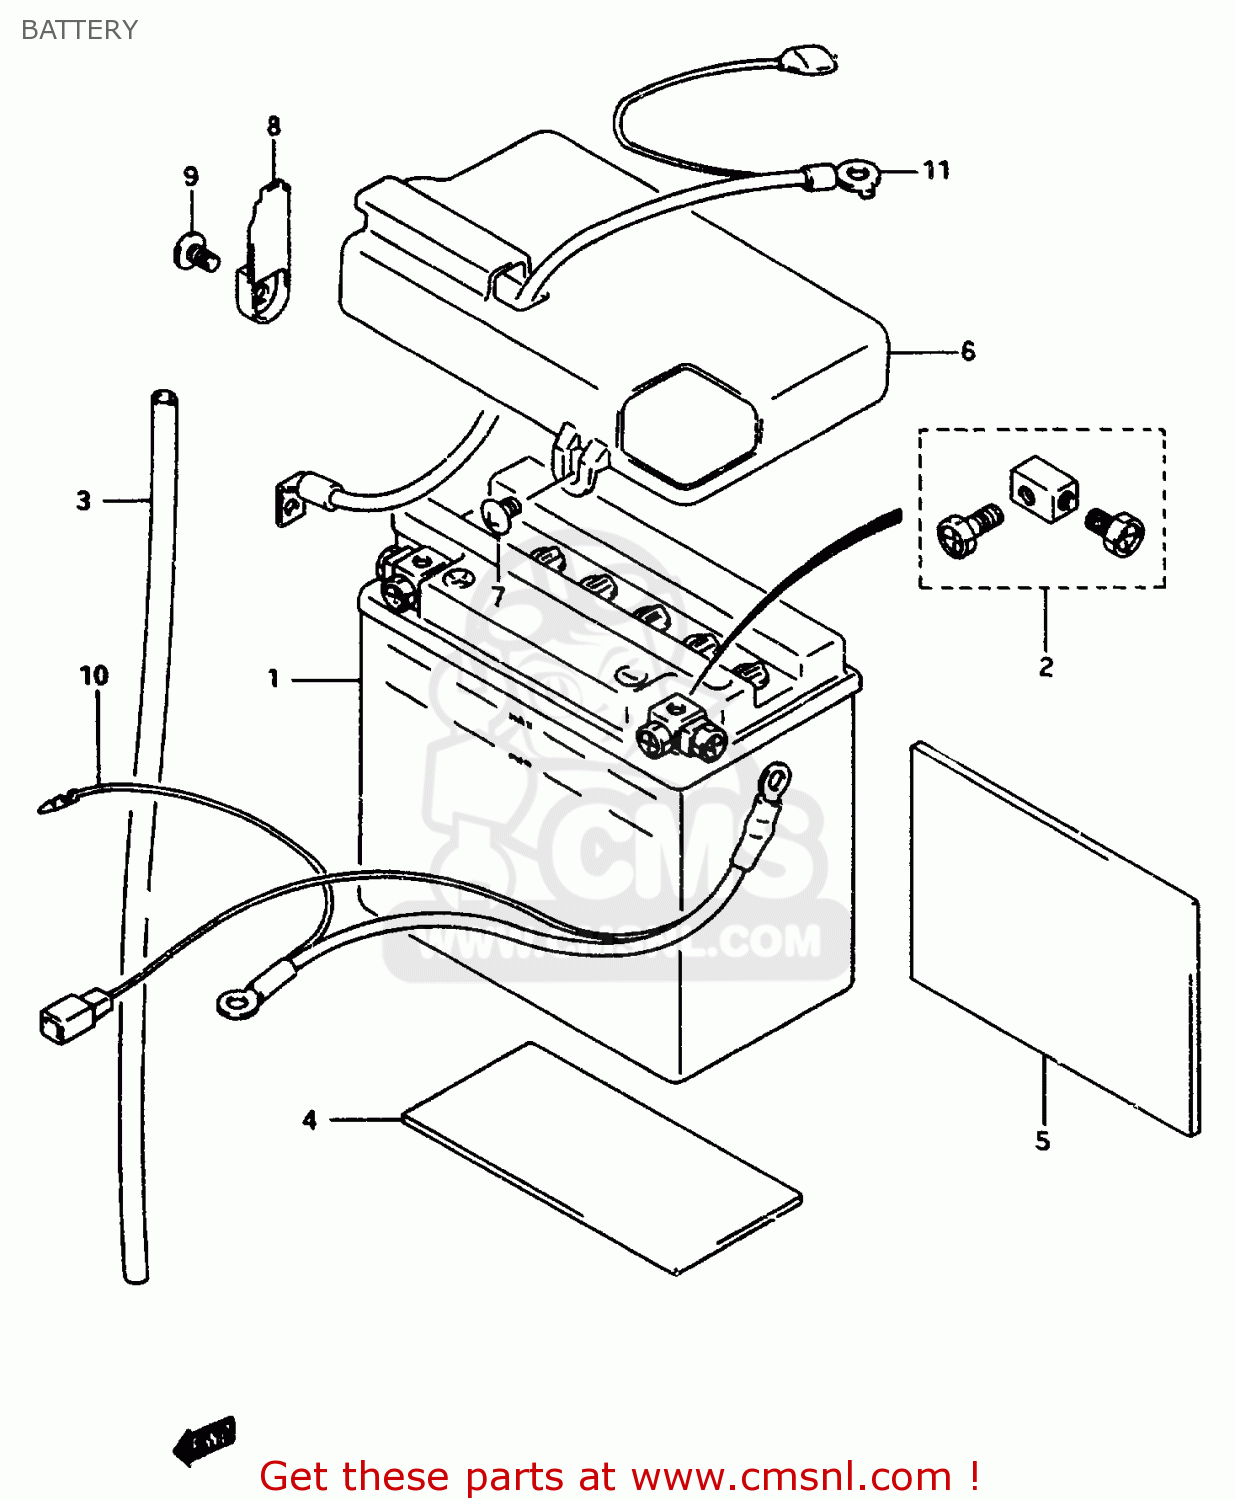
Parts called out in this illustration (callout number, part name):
1	BATTERY ASSY (12V)
2	BOLT SET,BATTERY TERMINAL
3	HOSE,BATTERY EXHAUST(L:780)
4	PROTECTOR(170X95X3.0)
5	PROTECTOR(80X80X2)
6	COVER,BATTERY UPR
7	SCREW
8	COVER,BATTERY TERMINAL
9	SCREW
10	WIRE,BATTERY PLUS LEAD
11	WIRE,BATTERY MINUS LEAD
